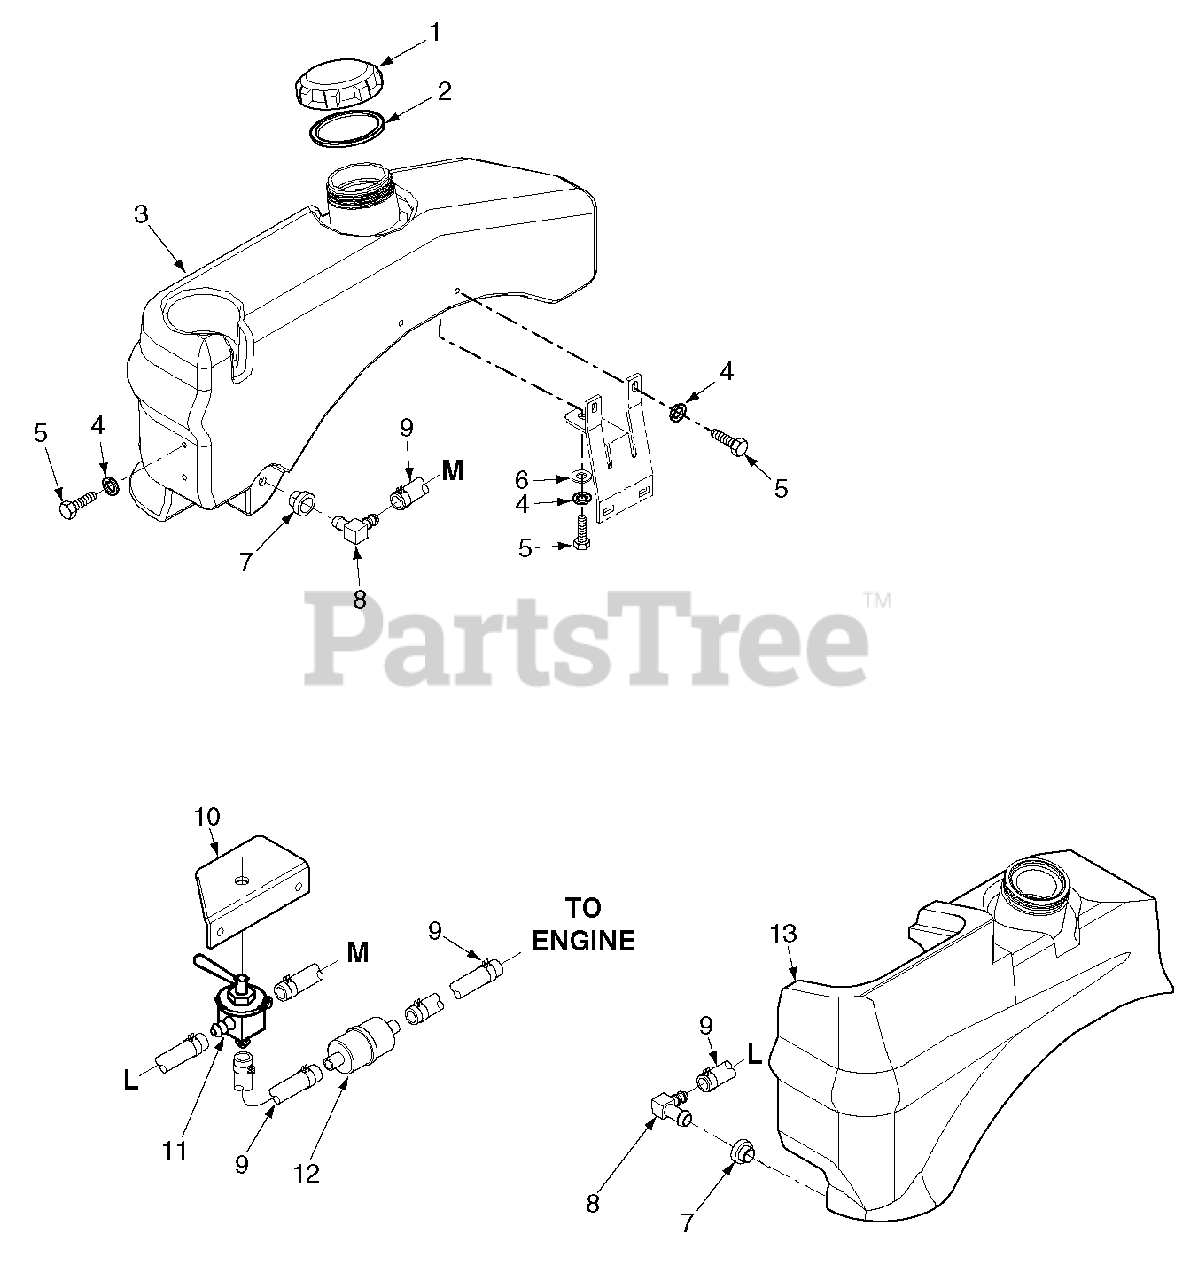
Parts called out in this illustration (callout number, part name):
1	Fuel Cap
2	Gasket, Fuel Cap
3	Fuel Tank RH
4	Lockwasher, 5/16" Spring
5	Bolt, Hex Head 5/16-18 x 3/4"
6	Flatwasher, 5/16-.375 x .875 x .083
7	Tank Bushing
8	Fitting, 90 Degree
9	Fuel Hose, 1/4" I.D. Non-Perm
10	Bracket, Fuel Valve
11	Fuel Shutoff Valve
12	Fuel Filter
13	Fuel Tank LH
